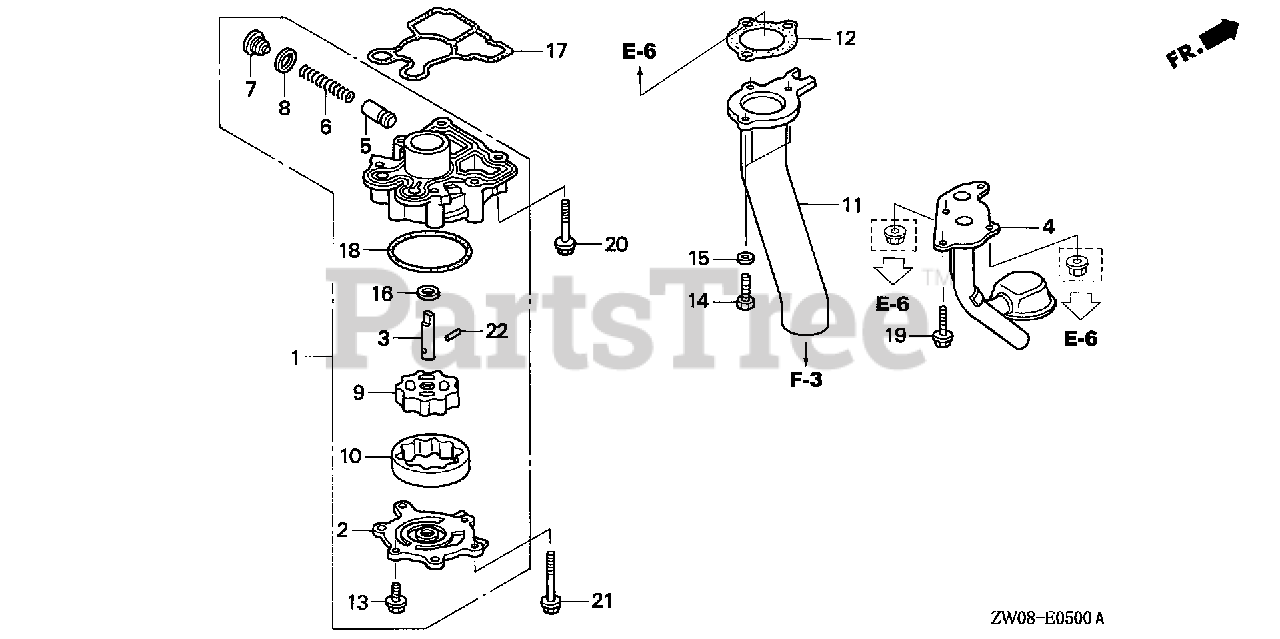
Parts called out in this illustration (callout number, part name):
1	PUMP ASSY., OIL
2	COVER, OIL PUMP
3	SHAFT, OIL PUMP
4	STRAINER, OIL
5	VALVE, RELIEF
6	SPRING, RELIEF VALVE
7	BOLT, SEALING (18MM)
8	WASHER, SEALING (18MM)
9	ROTOR (INNER)
10	ROTOR (OUTER)
12	GASKET, EX. PIPE
13	BOLT, FLANGE (6X18)
14	BOLT, HEX. (8X25)
15	WASHER, PLAIN (8MM)
16	WASHER, THRUST (12MM)
17	O-RING, OIL PUMP
18	O-RING, PUMP COVER
19	BOLT, FLANGE (8X20)
20	BOLT, FLANGE (8X40)
21	BOLT, FLANGE (8X65)
22	ROLLER (5X17.8)
